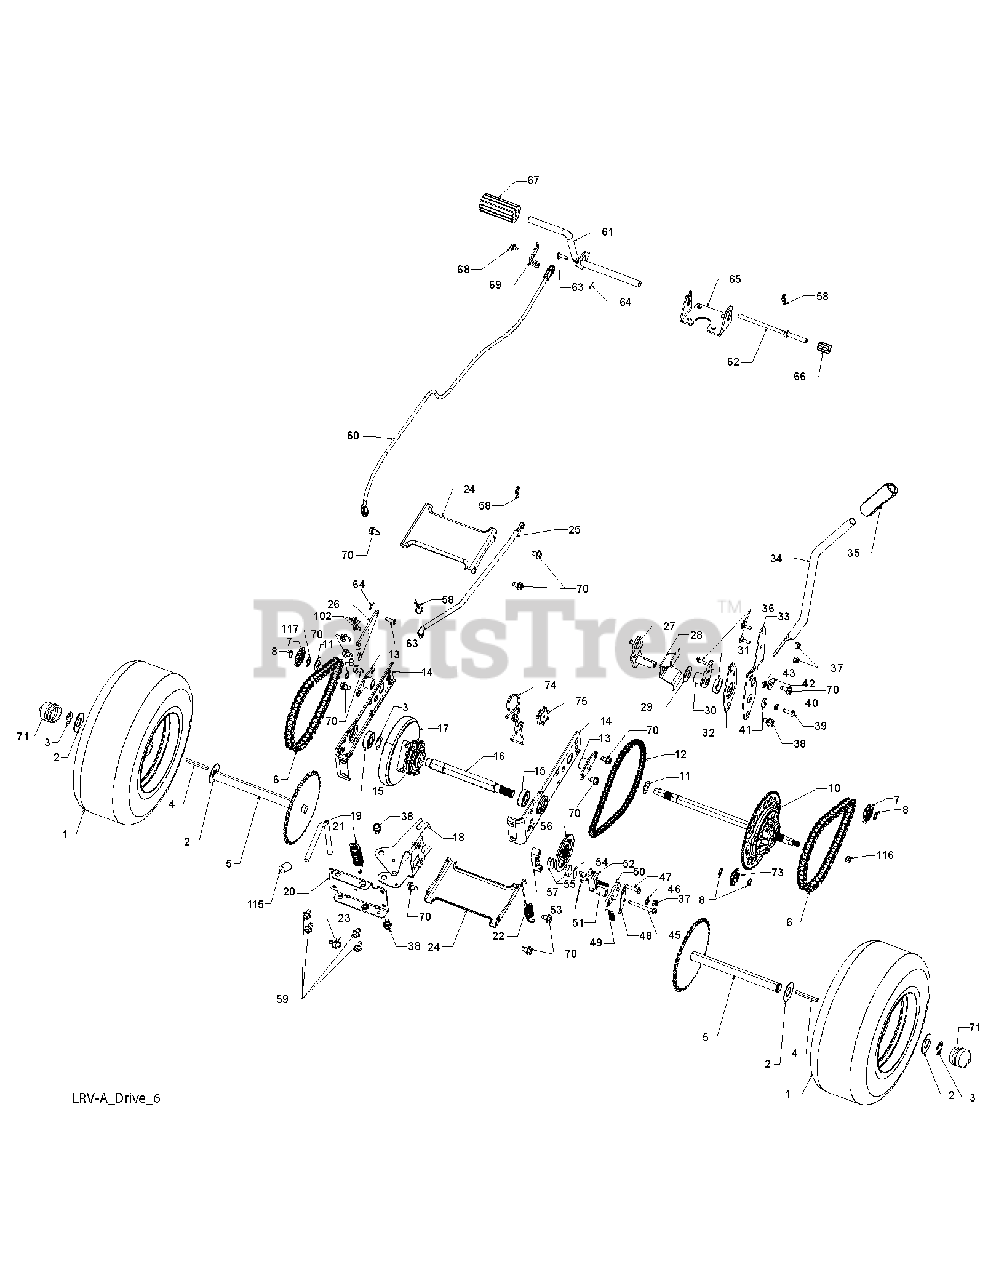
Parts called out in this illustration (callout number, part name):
1	Wheel Assembly, Rear 13" Gray
3	E-RING LT
4	SQUARE KEY
5	WELDMENT.AXLE.DRIVEN
6	CHAIN.DRIVE
7	SPROCKET.9.TOOTH.SPLINED
8	SNAP RING
10	DIFFERENTIAL ASM LRV
11	THRUST WASHER
12	CHAIN, PRIMARY DRIVE
13	BUSHING.FLANGE.5/8
14	BRACKET.CARRIER
15	BEARING.BALL
16	SHAFT.INPUT.LRV
17	SUBASM.WHEEL.FRICTION
18	ARM, SHIFT
19	ROD.BYPASS.LRV
20	BRACE CARRIER REAR
21	SPRING, CARRIER
22	SPRING, BRAKE
23	SPRING, BYPASS
24	BRACE CARRIER BOX
25	VALVE.COVER.LCT.414CC.
26	ARM. CLUTCH.LRV
27	WELDMENT SHIFT LEVER
28	RP SUPPORT, SHIFT LEVER
29	WASHER NYLON
30	HUB.SHIFT
31	SPACER.NYLON.
32	MNTG BRKT. SHIFT ARM
33	BRACKET, SHIFTER FLEX
34	TUBE SHIFT ARM
35	GRIP.HANDLE.LIFT.PVC.BLACK
37	LOCKNUT.NYLOC.1/4-20
38	BOLT.SHOULDER.5/16-18X
40	LOCKWASHER
41	WASHER LT
42	WASHER.SRRTD.5/16
43	NUT.71038.31-18.HEX.NYLOCK
45	SCREW.HXWH.THDRL.1/4-20X2.25
46	WASHER
47	SCREW.HXWH.THDRL.1/4-20X1-1/4
48	PLATE.ANTI-ROTATION.BRAKE
49	SPRING, BRAKE RETURN
50	ARM.BRAKE
51	SPACER.RETURN.BRAKE.LRV
52	CALIPER.BRAKE.ASM
53	PIN.DOWEL
54	PLATE, BRAKE PAD
55	PUCK BRAKE
56	ROTOR.BRAKE
57	CAP, BRAKE CALIPER
59	SCREW LT
60	CABLE.BRAKE.
61	SHAFT.ASM.PEDAL.LRV
62	ROD.BRAKE.PARK.LRV
63	PIN.CLEVIS
64	PIN.COTTER.5/64X3/4
65	BRACKET.SUPPORT.BRAKE.LRV
66	COVER.PEDAL.BRAKE.PARKING.LRV
67	COVER.PEDAL.BRAKE.LRV
68	SCREW.1/4-20X3/8
69	BRAKE.MOUNT.CABLE.LRV
70	SCREW
71	CAP.HUB.AXLE.LRVA/B
73	SPROCKET.11 TOOTH.SPLINED
74	TENSION.LRV.CHAIN
75	SPROCKET.IDLER.7TOOTH.LRV
115	CAP.PLUNGER.BLACK
116	NUT LOCK FLG 3/8-16 UNC
117	KLIP RING
